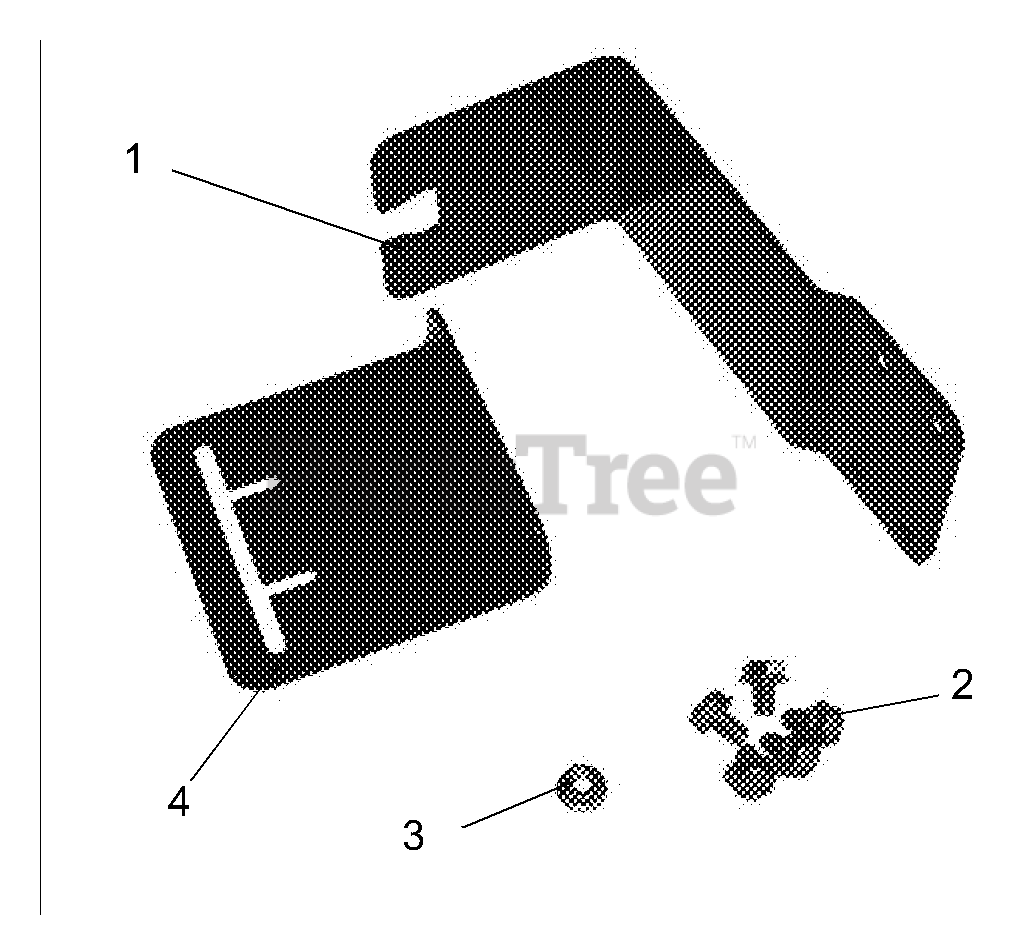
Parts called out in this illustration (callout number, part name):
1	Fuel Tank Mount
2	5/16"-18 x 1/2" Tapping Screw
3	5/16"-18 Top-Locking Flange Nut
4	Fuel Tank Bracket
